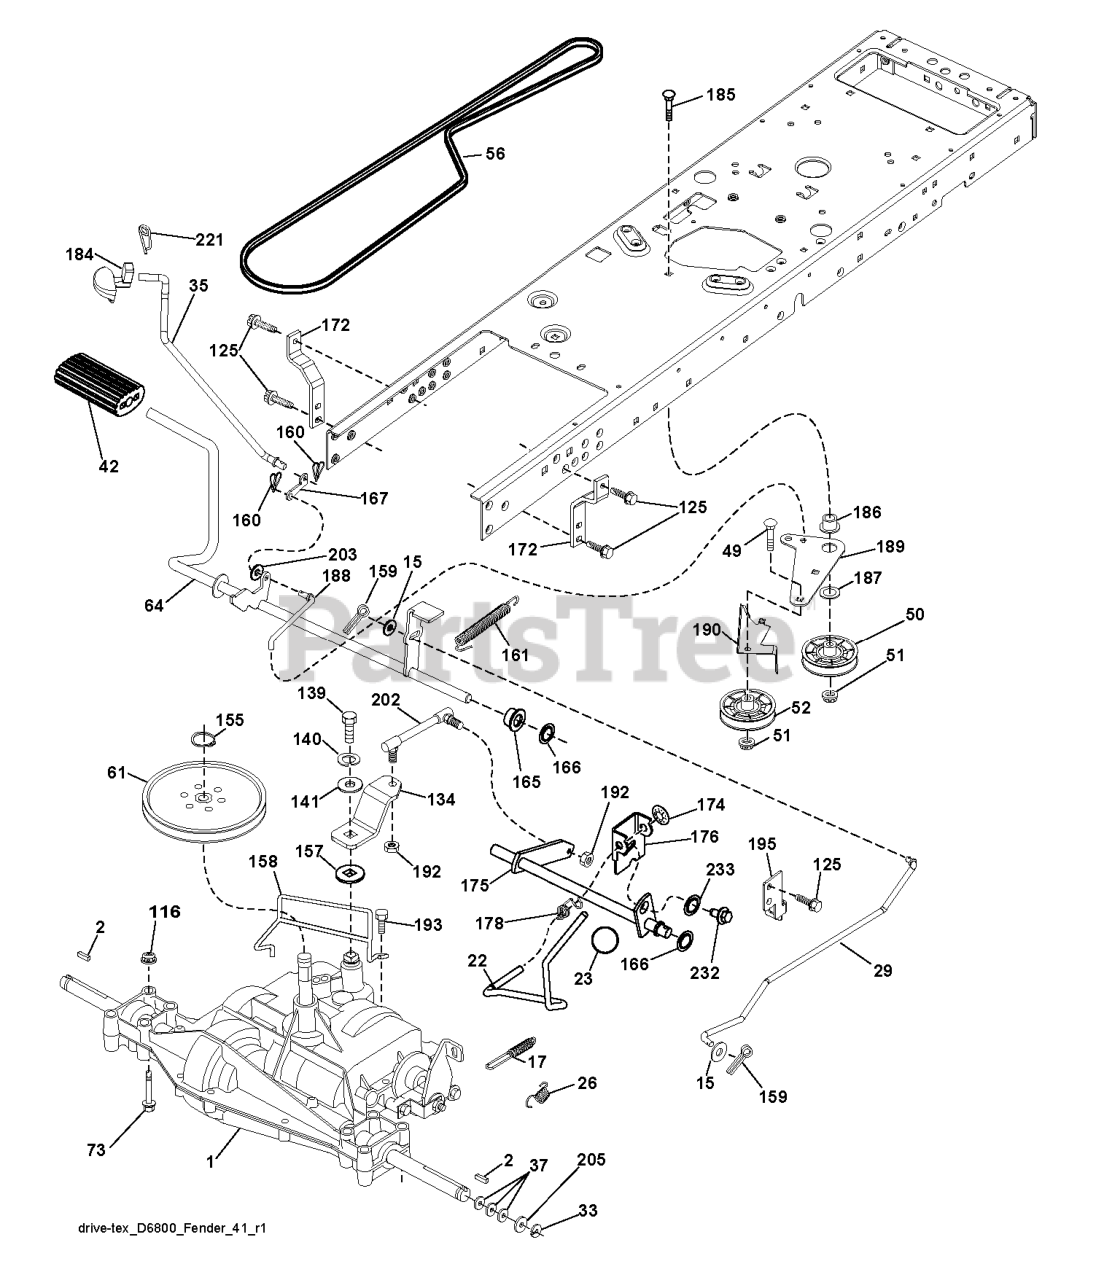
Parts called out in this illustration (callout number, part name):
2	SQUARE KEY
15	WASHER
17	SPRING.BRAKE.PEERLESS.TEX
22	ROD.SHIFT.FENDER.TLT.2006
23	KNOB.DUCKHEAD.1/2
26	SPRING.BRAKE.RTN.GR.DR
29	ROD.BRAKE.PEERLESS
35	ROD.CNTRL.PARK.PREDATOR.LT.TEX
42	PEDAL COVER T
50	IDLER.FLAT.910.OFFSET
51	NUT LOCK FLG 3/8-16 UNC
52	IDLER.V-GROOVE.910.OFFSET
56	V-BELT.TRACTOR.DRIVE.P
64	SHAFT.ASM.PEDAL.BRAKE.
73	BOLT HEX 5/16-18 GR 5
116	NUT LOCK HEX FLANGE 5/16-18
125	SCREW
134	ARM.SHIFT.
139	BOLT 1/4-28X3/4
140	LOCKWASHER
155	RETAINING RING LT
157	WASH-SHFT PLT LT
158	KEEPER.PMS.18/20.D4365
159	COTTER PIN
160	RETAINER CLIP
161	SPRING, RETURN LT
165	BUSHING.SHAFT.BRAKE.HAND
166	NUT.PUSH.625.2006
167	LATCH.BRAKE.SPRING
172	STRAP.TRQ.LH.GEAR.DRIV
174	NUT.PUSH.500.2006
175	SHAFT.ASM.SHIFT.
176	ARM.CLEVIS.ROD.SHIFT
178	SPRING.SHIFT.GT2006
184	HANDLE PARKING BRAKE
186	SPACER.RETAINER
187	WASHER 12/32X2X10GA
188	RP.LINK.CLUTCH.GROUND.DRIVE
189	BELLCRANK.GROUND.DRIVE.TEX.
190	KEEPER.BELLCRANK.DRIVE
192	NUT LOCK CENTER 1/4 -28 FNTHD
193	SCREW 5/16"
195	BRKT.ROD.BRAKE.PEERLES
202	LINK.TRANSAXLE.D6800.18/20"TEX
203	WASHER
221	RETAINER.SPRING.CLIP.H
232	BOLT FIN HEX 7/16-14 X 1
233	WASHER SERRATED
